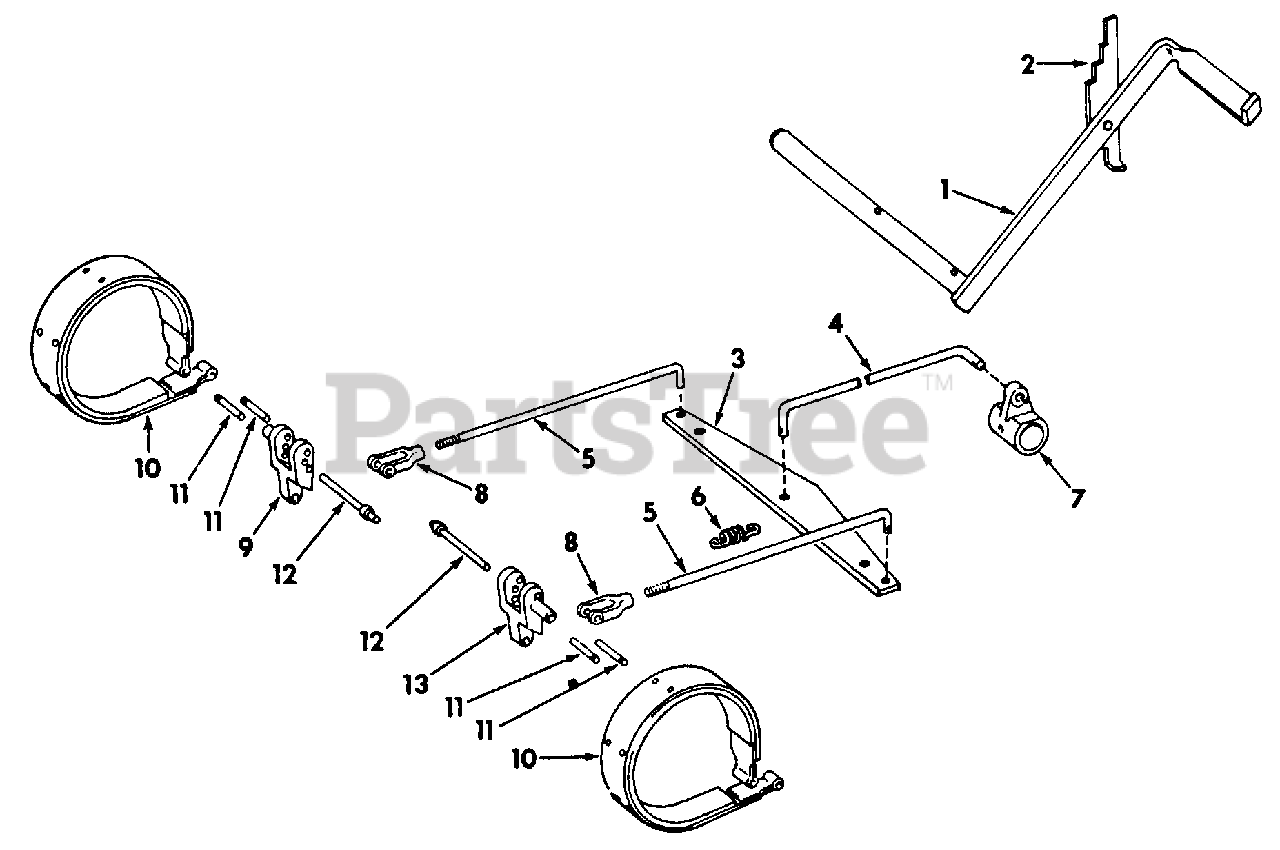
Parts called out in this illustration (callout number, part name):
1	PEDAL ASSY, BRAKE
2	STOP, RATCHET
3	BAR, EQUALIZER
4	ROD, EQUALIZER
5	ROD EQUALIZER BAR END
6	SPRING, RETURN
7	LEVER, BRAKE
8	CLEVIS, 5/16-24 X 2-1/4 LT ADJ ROD END BRAKE ROD
9	TOGGLE, LH ACTUATING
10	BAND W/LINING & RIVETS ASSY
13	TOGGLE, RH ACTUATING
